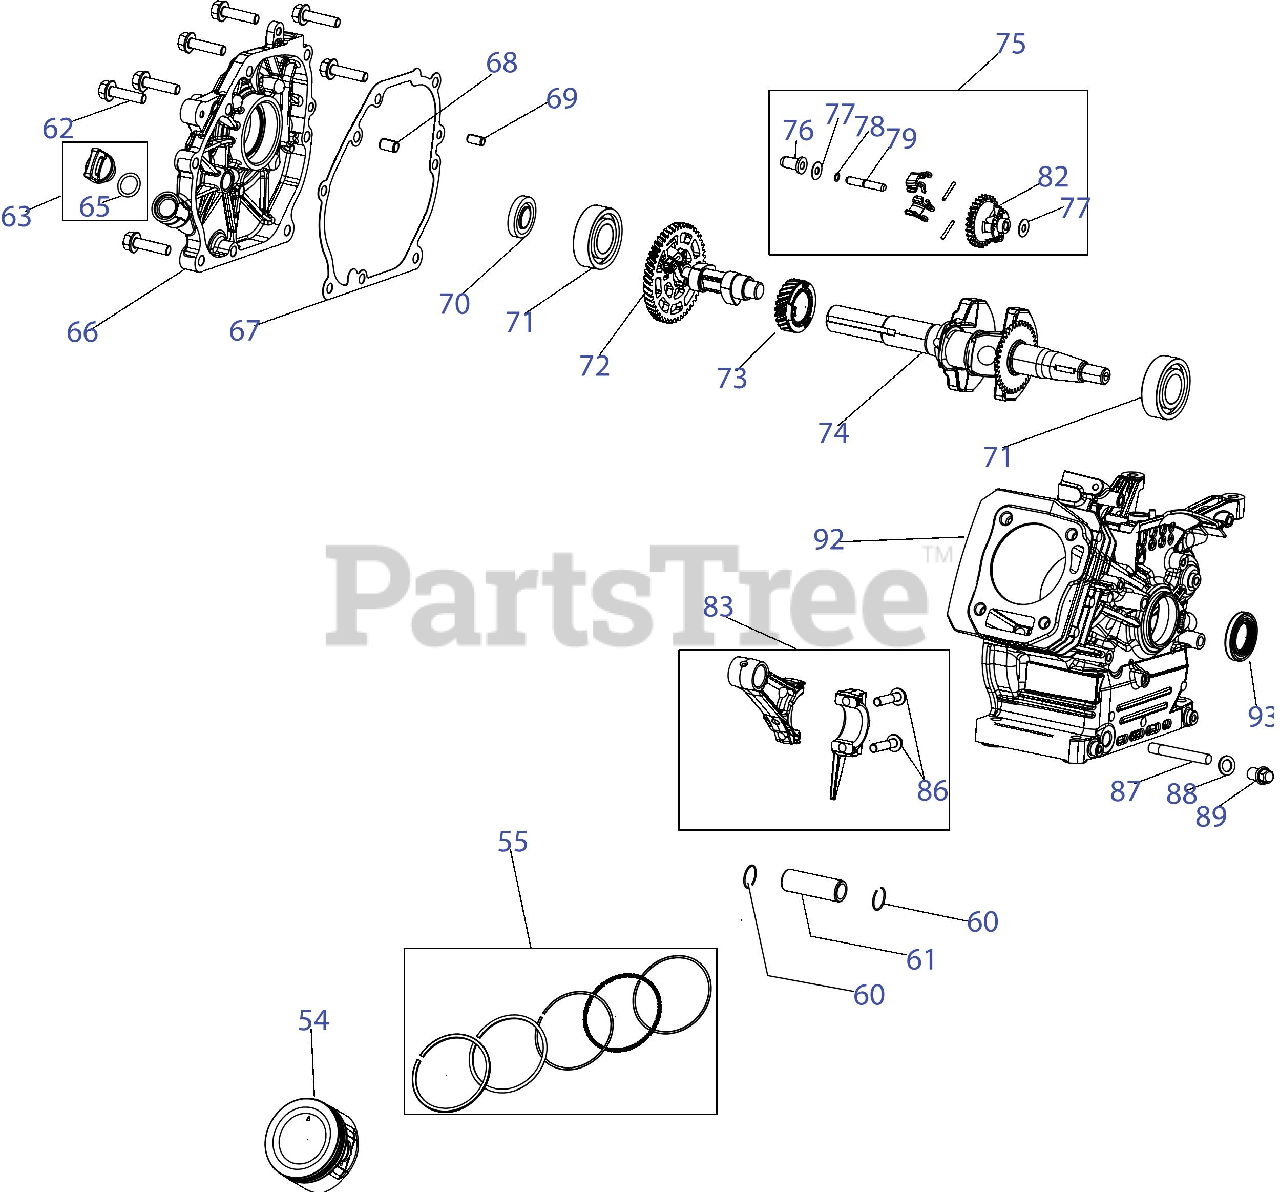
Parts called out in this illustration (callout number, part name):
55	Piston Ring Set
61	Piston Pin
62	Bolt, M8x32
65	O-Ring, 15.8x2.5
66	Crankcase Cover
67	Gasket, Crankcase
68	Pin, 9x14
69	Pin, 7x14
70	Oil Seal, 25x41.25x6
71	Bearing, 6205
73	Drive Timing Gear
74	Crankshaft
75	Governor Gear
76	Governor Cup
77	Washer, 6.2x0.6x15
78	Retaining Ring
79	Governor Shaft
82	Governor Gear
83	Connecting Rod Assembly
86	Connecting Rod Bolt
87	Oil Drain Pipe
88	Washer, 10x1.5x16
89	Earth Bolt
93	Oil Seal, 25x41.25x6
